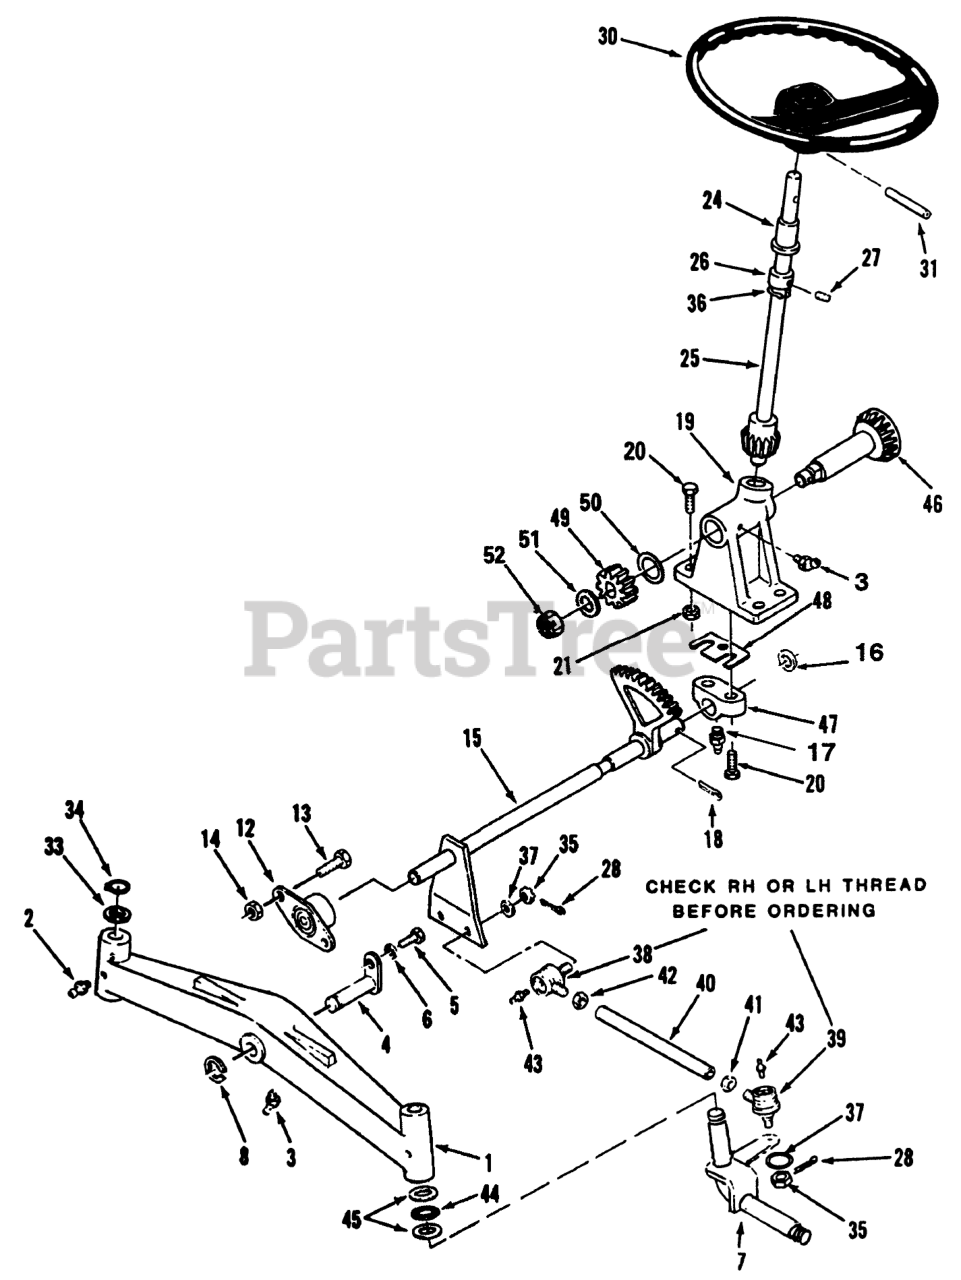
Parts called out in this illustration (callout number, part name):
1	Axle-Front
2	FITTING-GREASE
3	FITTING-GREASE
4	PIN AND PLATE ASM
5	SCREW-HH
6	WASHER-LOCK
7	Spindle
8	E-RING
12	BEARING-FLANGED
13	SCREW-HH
14	NUT-LOCK, NI
15	Shaft
16	Washer
17	ZERK FITTING
18	PIN-COTTER
19	Steering Support
20	SCREW-HH
21	NUT-LOCK, NI
24	BEARING-FLANGED
25	WLDMT-STRG SHAFT
26	COLLAR R
27	SCREW-HSH
28	PIN-COTTER
30	Steering Wheel
31	PIN-ROLL
33	WASHER
34	Snap Ring
36	RING-RETAINING
37	WASHER
38	SOCKET-BALLJOINT
39	SOCKET-BALLJOINT
40	Tube
41	NUT-HEX JAM 9/16-18
42	NUT-JAM
43	FITTING-GREASE
44	BEARING-THRUST
45	WASHER-THRUST
46	WLDMT-C SHAFT
47	BLOCK-BEARING
48	SHIM-.010
49	PINION-SPUR
50	Washer
51	Washer
52	Nut
